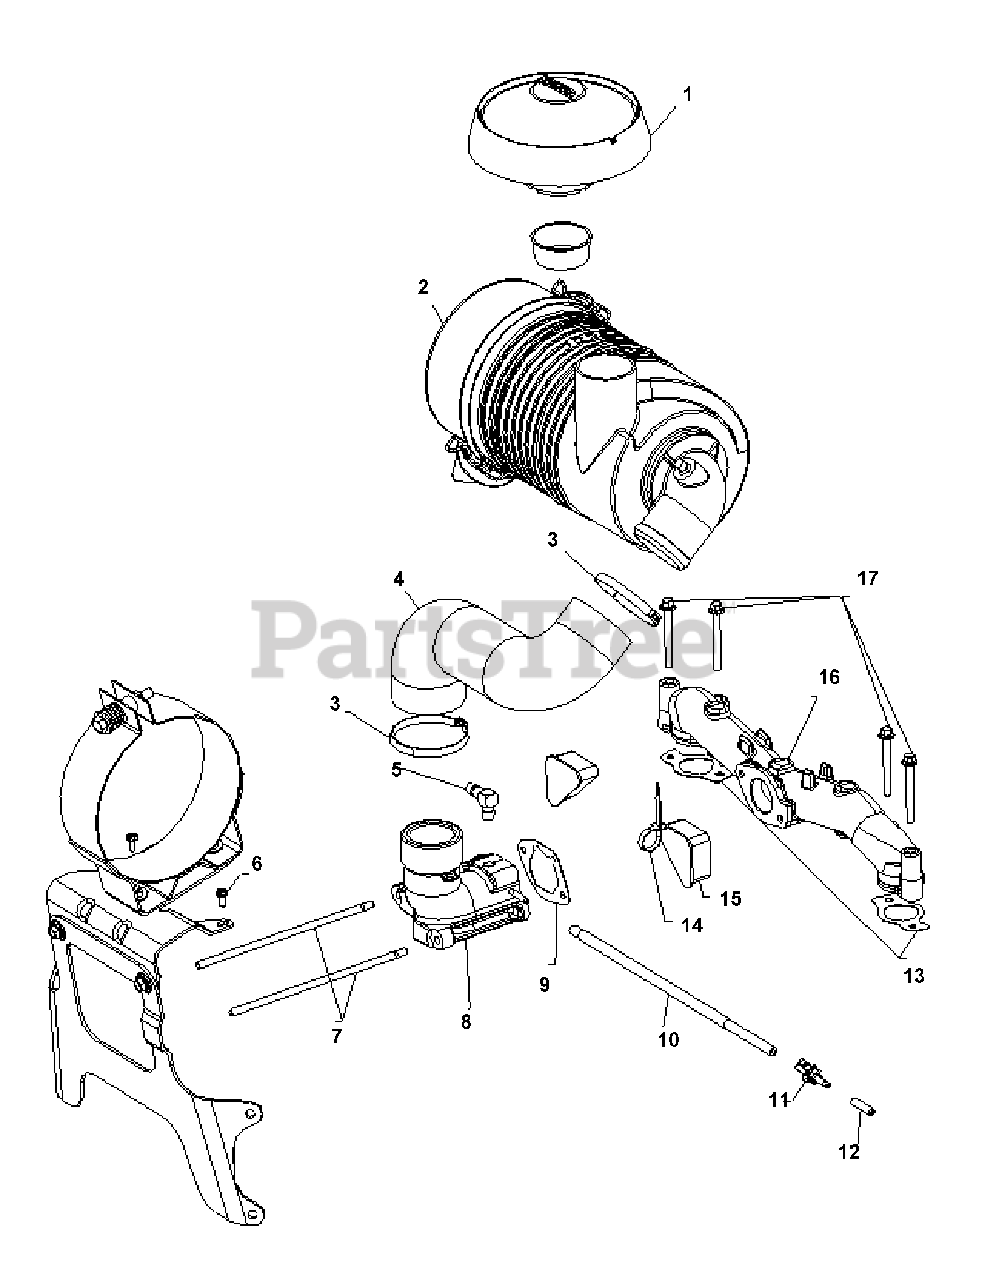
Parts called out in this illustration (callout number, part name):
4	Air Cleaner Hose
5	Hose Connecter
6	Screw, #8-18 x 1/2
7	Stude, M6 x 1.0 x 180
9	Air Cleaner Base Gasket
10	Evaporative Hose
11	Evaporative Connector
13	Intake Manifold Gasket
15	Blower Housing Cover
16	Intake Manifold
17	Screw, M6 x 1.0 x 55
